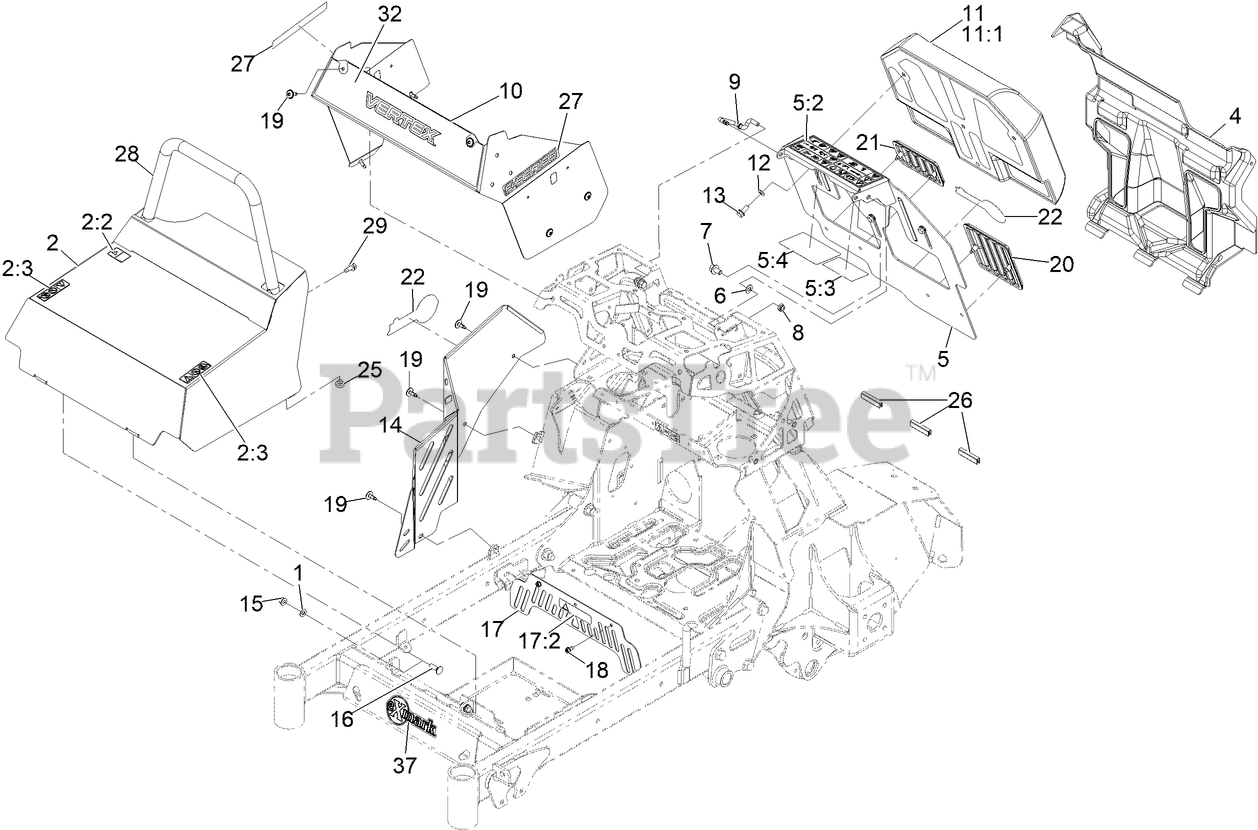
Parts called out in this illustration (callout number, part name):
1	SPACER-NYLON
2	ASM-Cover W Decals
2:2	DECAL-WARNING
2:3	DECAL-NO STEP/RIDERS
4	COVER-REAR STE
5	ASM, PAD BACKING W/ DECALS
5:2	DECAL-WARNING
5:3	DECAL-DRIVE RELEASE
5:4	DECAL-SERVICE AID SM
6	WASHER-THRUST
7	SCREW-HHF
9	ROD, PROP
10	SKIN TOWER
11	PAD-THIGH
11:1	Cover Pad
12	WASHER-BELLEVILLE
13	SCREW-HHF
14	Cover-Rt Side
16	BOLT-CARR
17	ASM, BELT GUARD W/ DECAL
17:2	DECAL-WARNING
18	SCREW-HWH
19	SCREW, TORX
20	PAD, KNEE, LT
21	PAD, KNEE, RT
22	DECAL-EXMARK LOGO
26	STRIP-SEAL 2.13
27	DECAL-E-SERIES
28	TUBE-GUARD MUFFLER
29	SCREW-THD ROLL, HWH
32	DECAL-FRONT PANEL
37	DECAL-EXMARK LOGO
